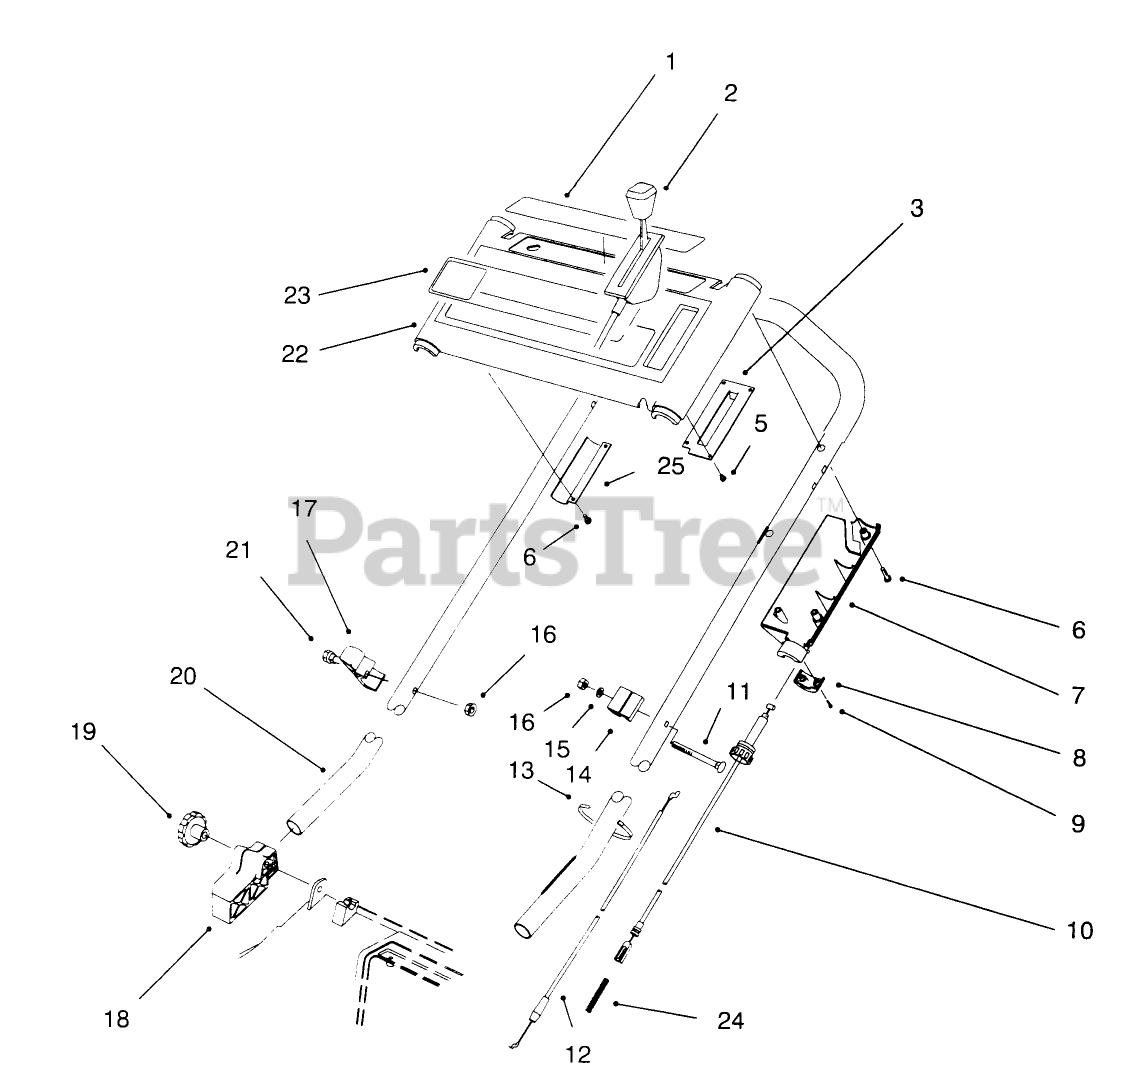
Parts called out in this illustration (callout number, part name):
1	DECAL - CONTROL PANEL
2	CONTROL - THROTTLE
5	#6-19X.25 PLASK FORM SC
6	SCREW-PPH, PLASTITE
7	COVER-THROTTLE, LEVER
8	LOWER THROTTLE CAP
10	ASM - TRACTION CABLE
11	SCREW-HANDLE
12	CABLE - BRAKE
13	TIE-CABLE
14	SUPPORT-CABLE
15	WASHER-FLAT
16	NUT-LOCK, NI
17	GUIDE - ROPE
18	MOUNT-HANDLE, RH
24	SPRING-COMPRESSION
